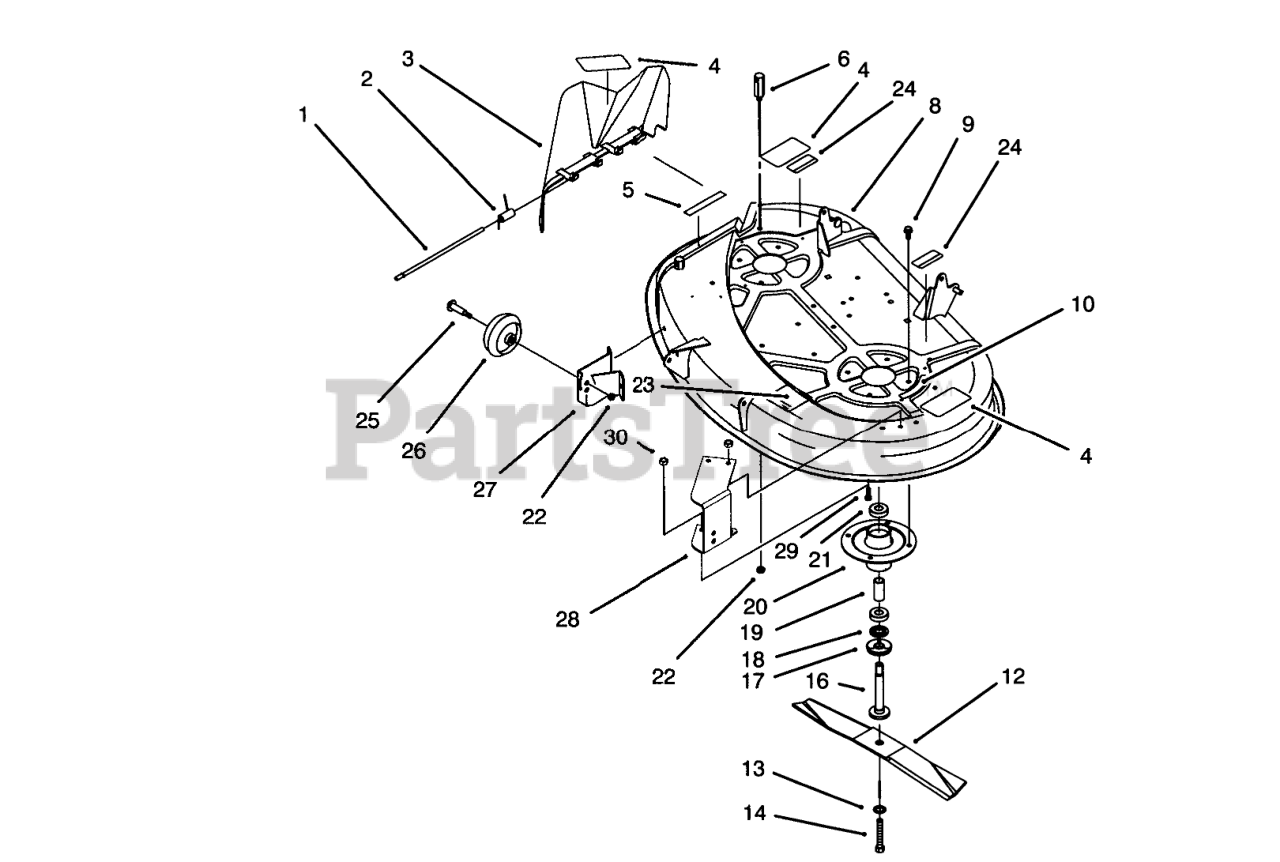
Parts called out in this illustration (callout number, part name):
1	ROD-HINGE DEFLECTOR
2	SPRING
3	Deflector Ass-y (Incl. Ref. #4)
4	DECAL-DANGER
5	DECAL-DANGER
6	REAR PIVOT POST (PLTD)
8	Deck-38"
9	SCREW-TAPTITE
10	DECAL-DANGER, SHIELD
12	Blade
13	WASHER-BELLEVILLE
14	SCREW-HH
16	SHAFT-SPINDLE
17	SHIELD-BEARING
18	SPACER
19	SPACER
20	HOUSING-SPINDLE
21	BEARING-BALL
22	NUT-LOCK, NI
23	DECAL-ROUTING, BELT
24	DECAL-WARNING
25	SCREW-SHOULDER, HWH
26	WHEEL-GAGE
27	Bracket-R.H.
28	Bracket-L.H.
29	SCREW-HH
30	NUT-LOCK, NI
